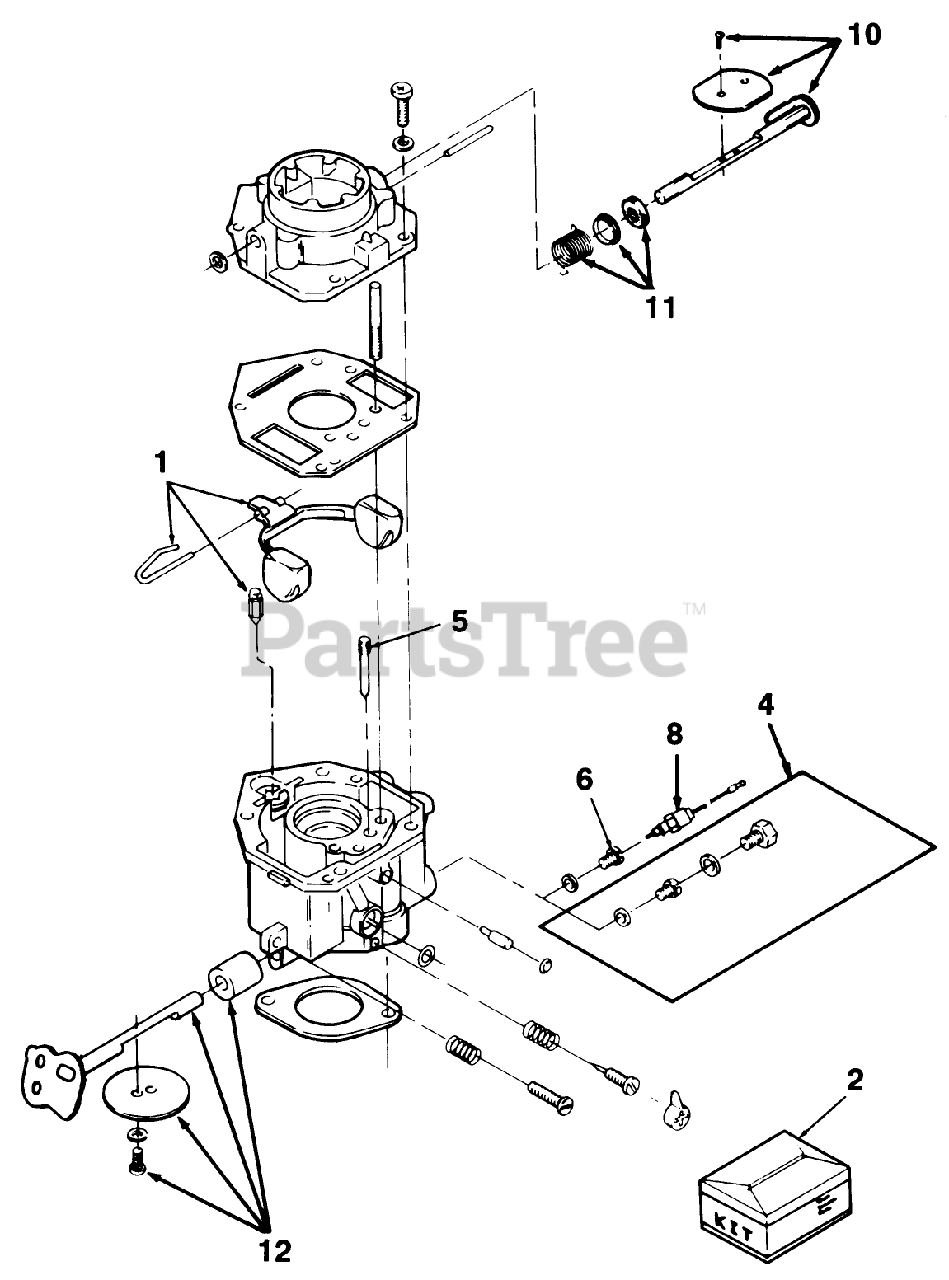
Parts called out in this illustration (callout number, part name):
1	FLOAT
2	REPAIR KIT
4	JET-FIXED, HIGH ALTITUDE
5	JET-IDLE
6	JET-POWER
8	SOLENOID - FUEL CUT OFF
10	CHOKE KIT SHAFT
12	THROTTLE SHAFT KIT
